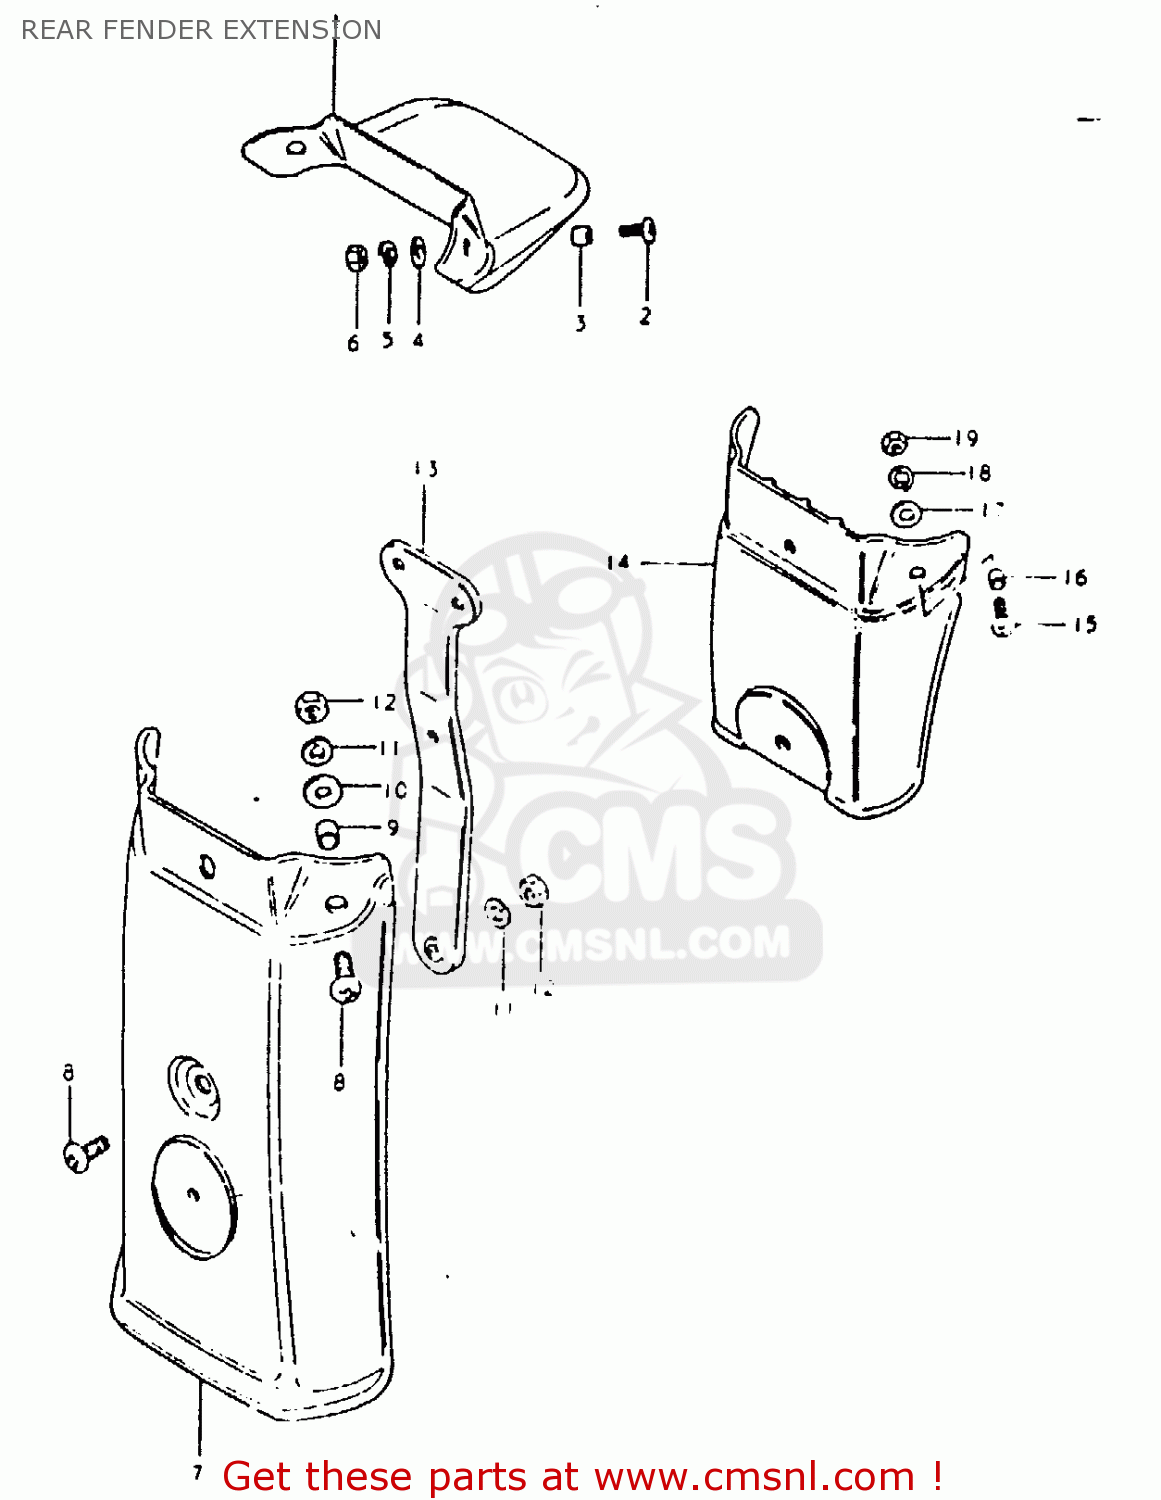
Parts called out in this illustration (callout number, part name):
1	EXTENSION,REAR FENDER
2	SCREW (6X15)
3	SPACER(6.2X8.3X5.7)
4	WASHER(6.5X18X1)
5	LOCK WASHER
6	NUT
